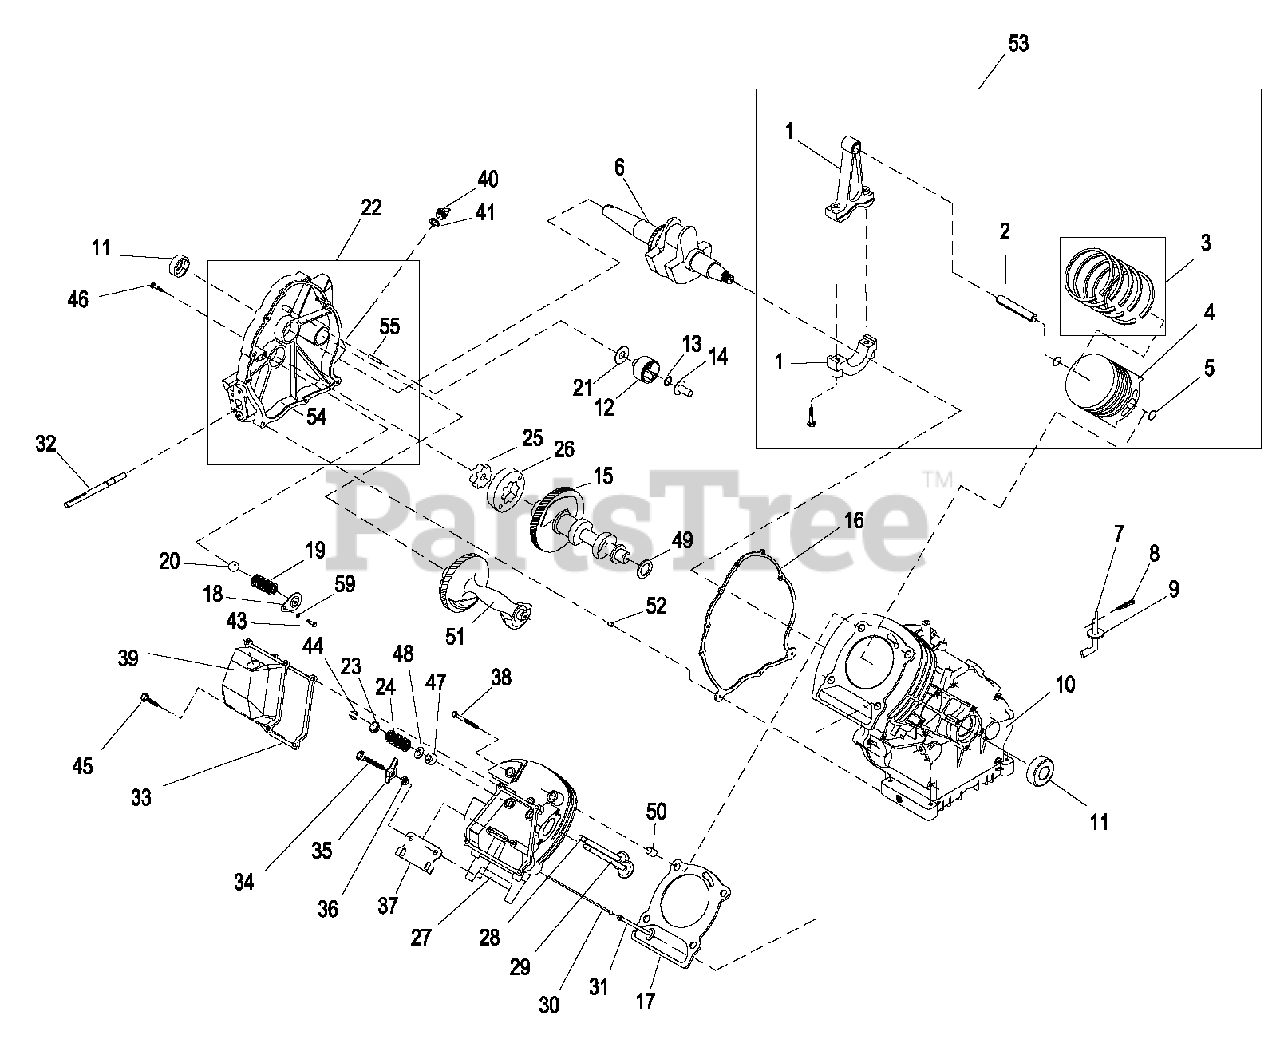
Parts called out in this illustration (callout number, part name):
1	ASSEMBLY' CONNECTING ROD
2	PIN' PISTON D20
3	RING SET' PISTON Ø90
4	PISTON' FLAT TOP Ø90 COATED
5	RETAINER' PISTON PIN 20
6	ASSEMBLY' CRANKSHAFT GH410 SMALL TAPER
7	ARM' GOVERNOR RC45
8	PIN COTTER "R" .059 X 1/4 X 1-1/8
9	WASHER' GOVERNOR ARM THRUST
10	CRANKCASE' SUBASSEMBLY WITH PLUGS GH410
11	SEAL' 35 I.D. CRANKSHAFT
12	ASSEMBLY' GOVERNOR GEAR
13	RING' GOVERNOR GEAR RETAINER
14	SPOOL' GOVERNOR- MACHINE
15	ASSEMBLY' CAMSHAFT & GEAR
16	GASKET ' CRANKCASE
17	GASKET' HEAD 410
18	COVER' OIL PRESSURE RELIEF
19	SPRING' OIL RELIEF 360
20	BALL' DIA 11/32 PRESSURE RELIEF
21	WASHER' THRUST GOVERNOR GEAR
22	ASSEMBLY' COVER
23	RETAINER' VALVE SPRING
24	VALVE SPRING LF
25	GEROTOR' INNER 12 THK
26	GEROTOR' OUTER 12 THK
27	ASSEMBLY'CYLINDER HEAD SEATS & GUIDES
28	VALVE' EXHAUST
29	VALVE' INTAKE
30	PUSH ROD 174.9
31	TAPPET
32	ASSEMBLY' SCREEN OIL PICK-UP
33	GASKET' ROCKER COVER 410
34	STUD' D20 PIVOT BALL
35	ROCKER ARM
36	NUT' JAM M8 (ROCKER ARM)
37	PLATE' PUSH ROD GUIDE
38	SCREW' HHFL M10-1.5 X 105
39	ASSEMBLY' ROCKER COVER OHVI
40	PLUG' OIL FILL PLASTIC ORANGE
41	O-RING 11/16 – 7/8
43	SCREW HHC M5-0.8 X 10 C8.8
44	KEEPER' VALVE SPRING
45	SCREW HHFCS M6-1 X 12 G8.8
46	SCREW' HHFC M8-1.25 X 42
47	SEAL' VALVE STEM D7
48	WASHER' VALVE SPRING
49	WASHER' LARGE WAVE
50	SLEEVE' DOWEL PIN 14 DIA.
51	BALANCER
52	SLEEVE' DOWEL PIN 12 DIA.
53	ASSEMBLY' PISTON PIN & CONNECTING ROD
54	GEARCOVER' MACHINED
55	SHAFT' GOVERNOR
59	WASHER' LOCK M5
